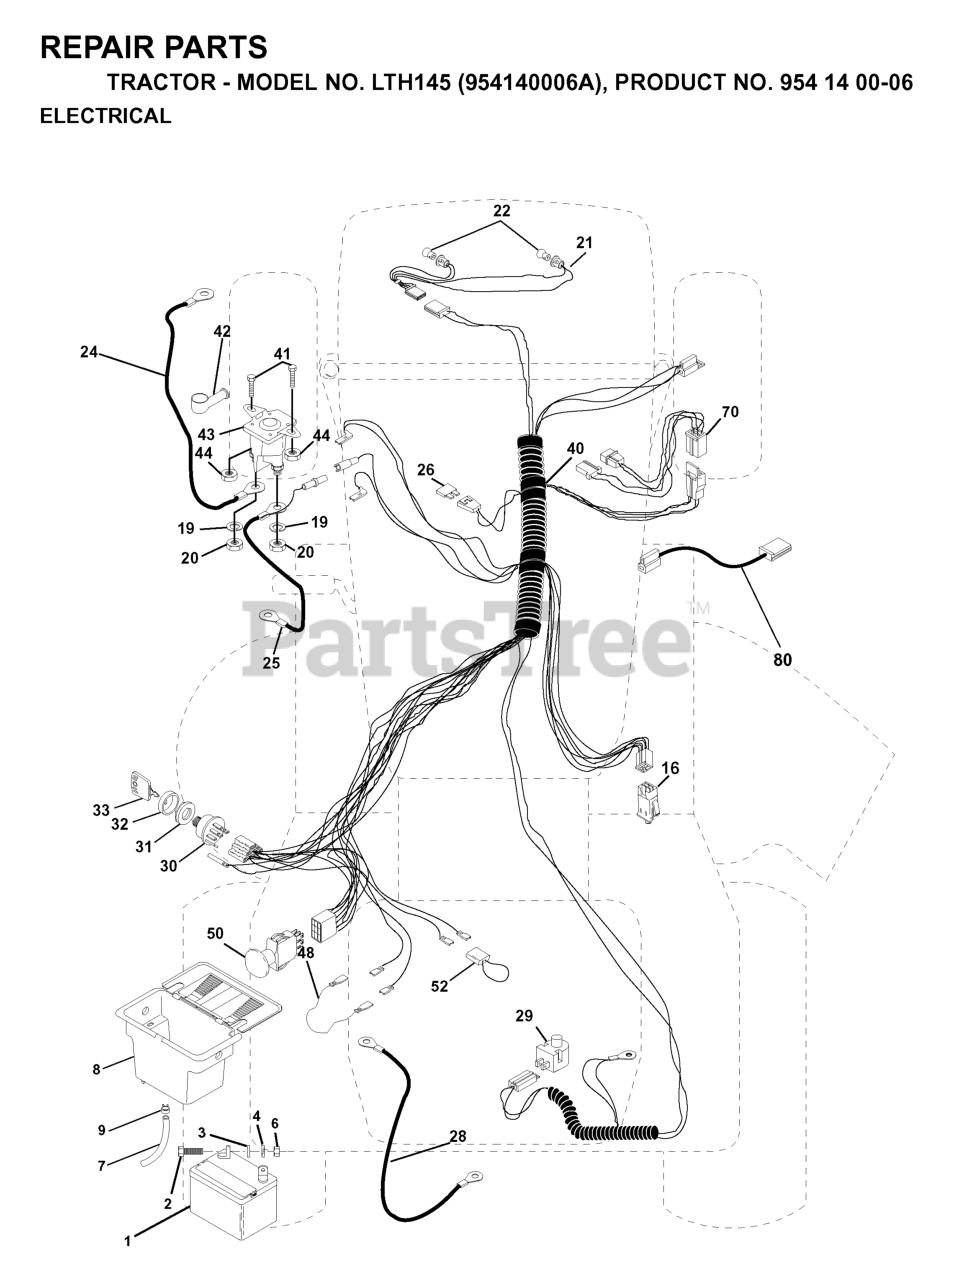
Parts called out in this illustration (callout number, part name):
1	BATTERY
2	BOLT.HEX.1/4.X.3/4.DICHROMATE
4	LOCKWASHER
6	NUT
7	TUBE BATTERY DRAIN
8	CASE BATTERY MECH HINGE
9	HOSE CLAMP T
16	SWITCH INTERLOCK
19	LOCKWASHER
20	NUT
21	HARNESS LIGHT SOCKET
24	BATTERY CABLE GT
25	CABLE BATTERY
28	CABLE T
29	RP.SWITCH.PLUNGER.NC.GRAY
30	SWITCH.IGNITION.4.POSITION
31	NUT IGNITION
32	COVER SWITCH KEY
33	KEY.MOLDED.GENERIC
40	IGN HARNESS
41	BOLT
42	TERMINAL COVER
43	SOLINOID
44	Nut, Keps Blk Hex 1/4-20 UNC
48	ADAPTER.AMMETER
50	SWITCH PTO 3 PDT
52	WIRE PROTECTION LOOP
70	HARNESS ENGINE
80	HARNESS, CLUTCH
